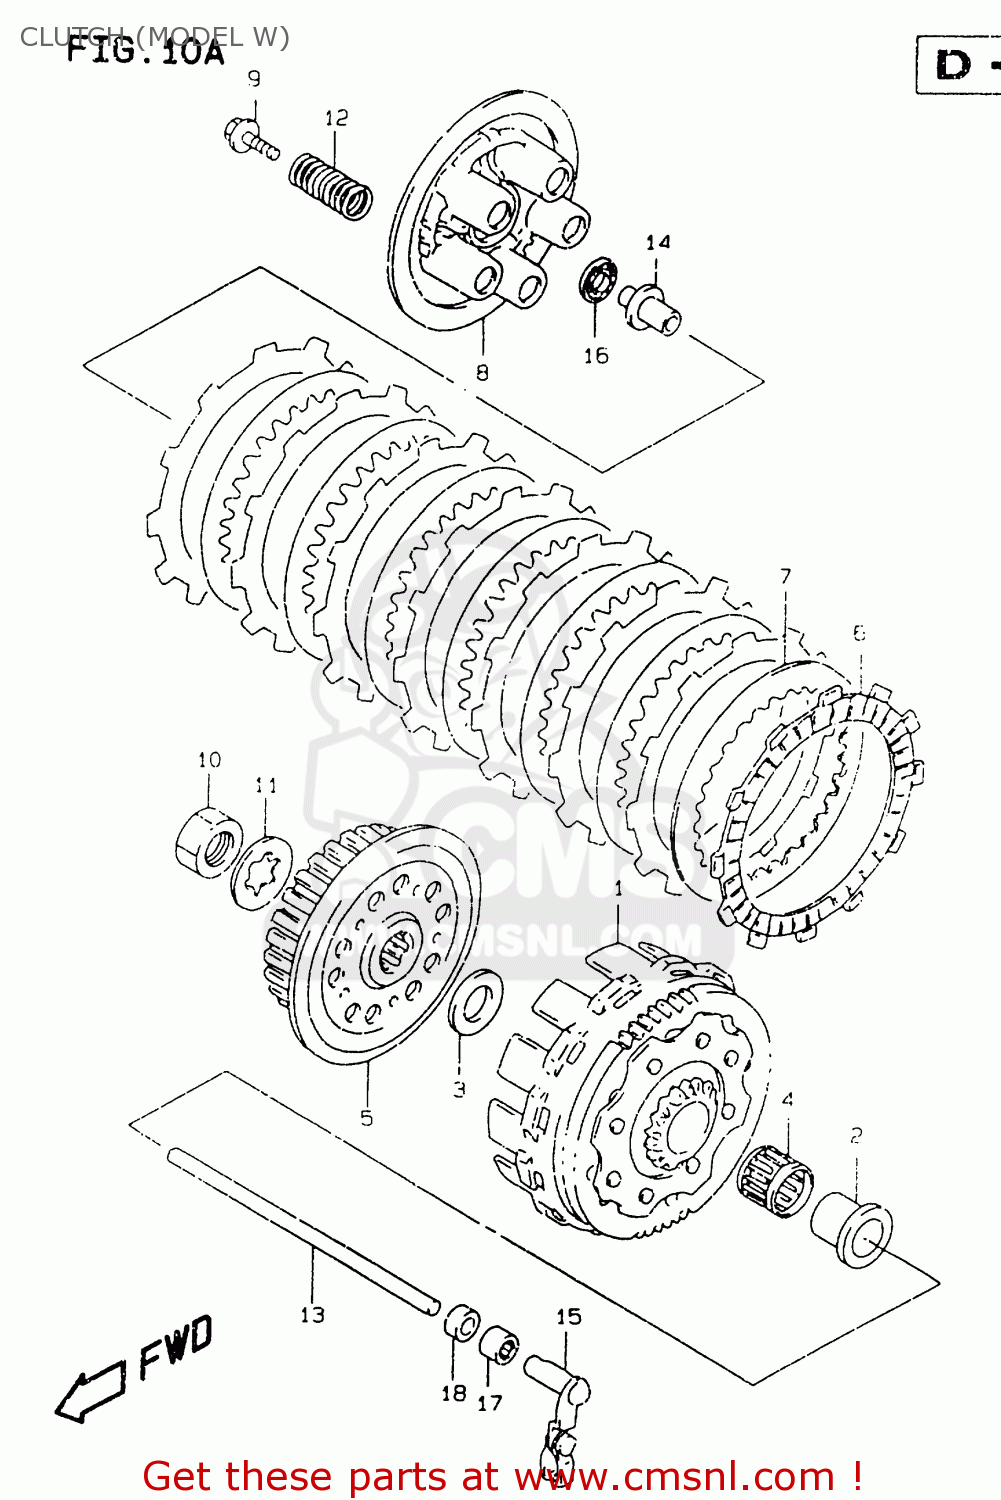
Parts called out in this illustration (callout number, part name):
1	GEAR ASSEMBLY,PRIMARY (NT:6
2	SPACER,PRIMARY DRIVEN GEAR
3	WASHER
4	BEARING(25X30X22)
5	HUB,CLUTCH SLEEVE
6	PLATE,CLUTCH DRIVE T:2
7	PLATE,CLUTCH DRIVEN T:
8	DISC,CLUTCH PRESSURE
9	BOLT(5X25)
10	NUT
11	WASHER,LOCK
12	SPRING
13	ROD,CLUTCH PUSH
14	PIECE,CLUTCH PUSH
15	CAMSHAFT,CLUTCH RELEASE
16	BEARING(10X22X2.8)
17	BEARING(10X14X15)
18	SEAL,OIL(10X17X5)
